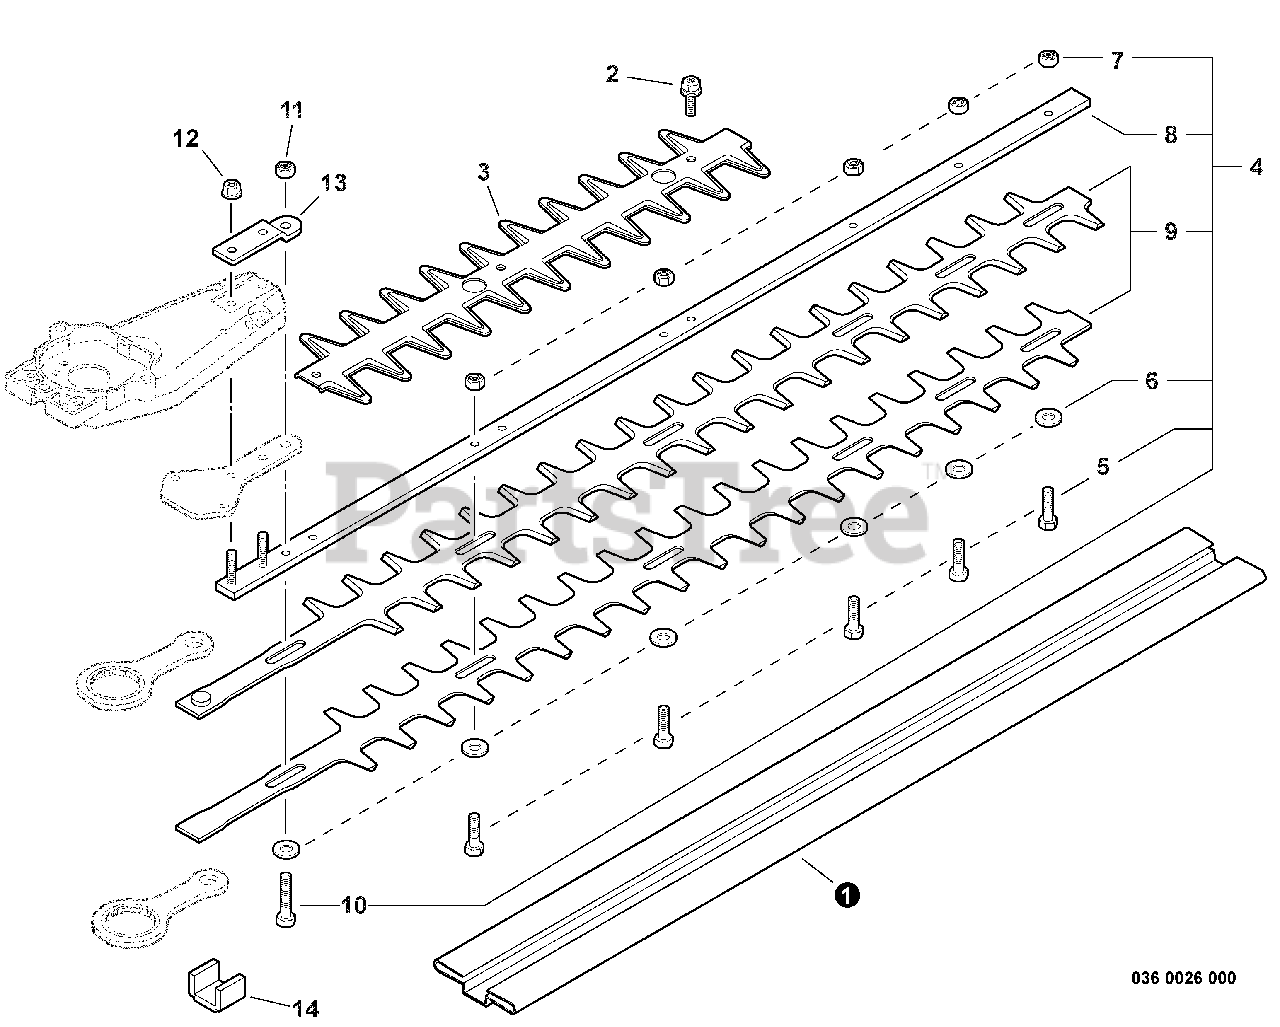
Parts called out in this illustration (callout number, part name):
1	COVER, BLADE - 30" (76cm)
2	BOLT - 5X8
3	SHIELD, BLADE
4	BLADE KIT - 30" (76cm) CHROME
5	BOLT - 6X20
6	WASHER - 6
7	LOCKNUT - 6
8	SUPPORT, BLADE - 30" (76cm)
9	BLADE - 30" (76cm) -- CHROME
10	BOLT - 6
11	LOCKNUT - 6
12	NUT - 5 -- FLANGE
13	PLATE, ANGLE
14	SEAL, FELT
